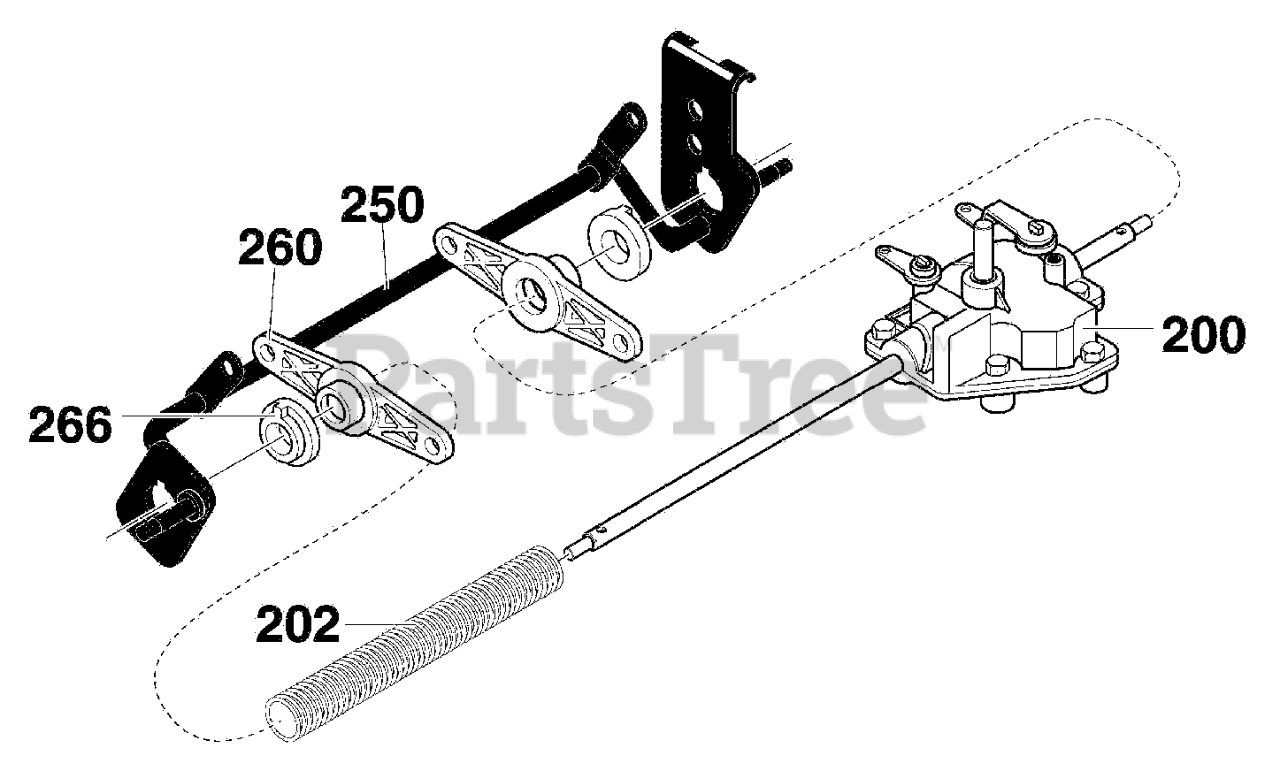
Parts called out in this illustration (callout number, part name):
200	Transmission 3 Speed
202	SHIELD, Axle
250	Crossbar Assy. Rear
260	SUPPORT, Axle W/Bearing
266	BEARING, Lifter
